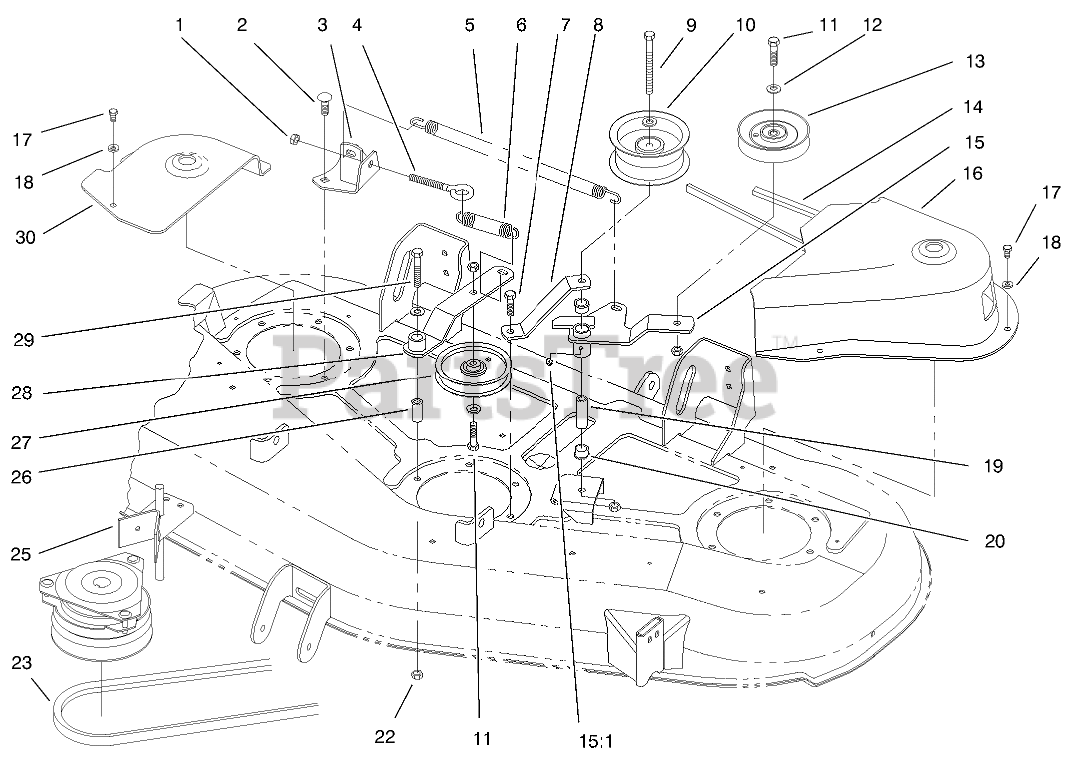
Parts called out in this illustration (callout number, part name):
1	NUT-LOCK, NI
2	SCREW-CARR
3	BRACKET-SPRING
4	BOLT-EYE
5	SPRING-EXTENSION
6	SPRING-EXTENSION
7	SCREW-HH
8	STRAP-SUPPORT
9	SCREW-HH
10	PULLEY-IDLER
11	SCREW-HH
12	WASHER-FLAT
13	PULLEY-IDLER
14	V-BELT
15	IDLER ARM ASSEMBLY
15:1	FITTING-GREASE
16	COVER-BELT, LH
17	SCREW-HWH
18	WASHER-FLAT
19	SPACER
20	BUSHING
22	NUT-HF
23	BELT - V
25	DECK UPSTOP ASSEMBLY
26	SLEEVE
27	PULLEY-IDLER
28	IDLER ARM ASM
29	SCREW-HH
30	COVER - BELT, RH
